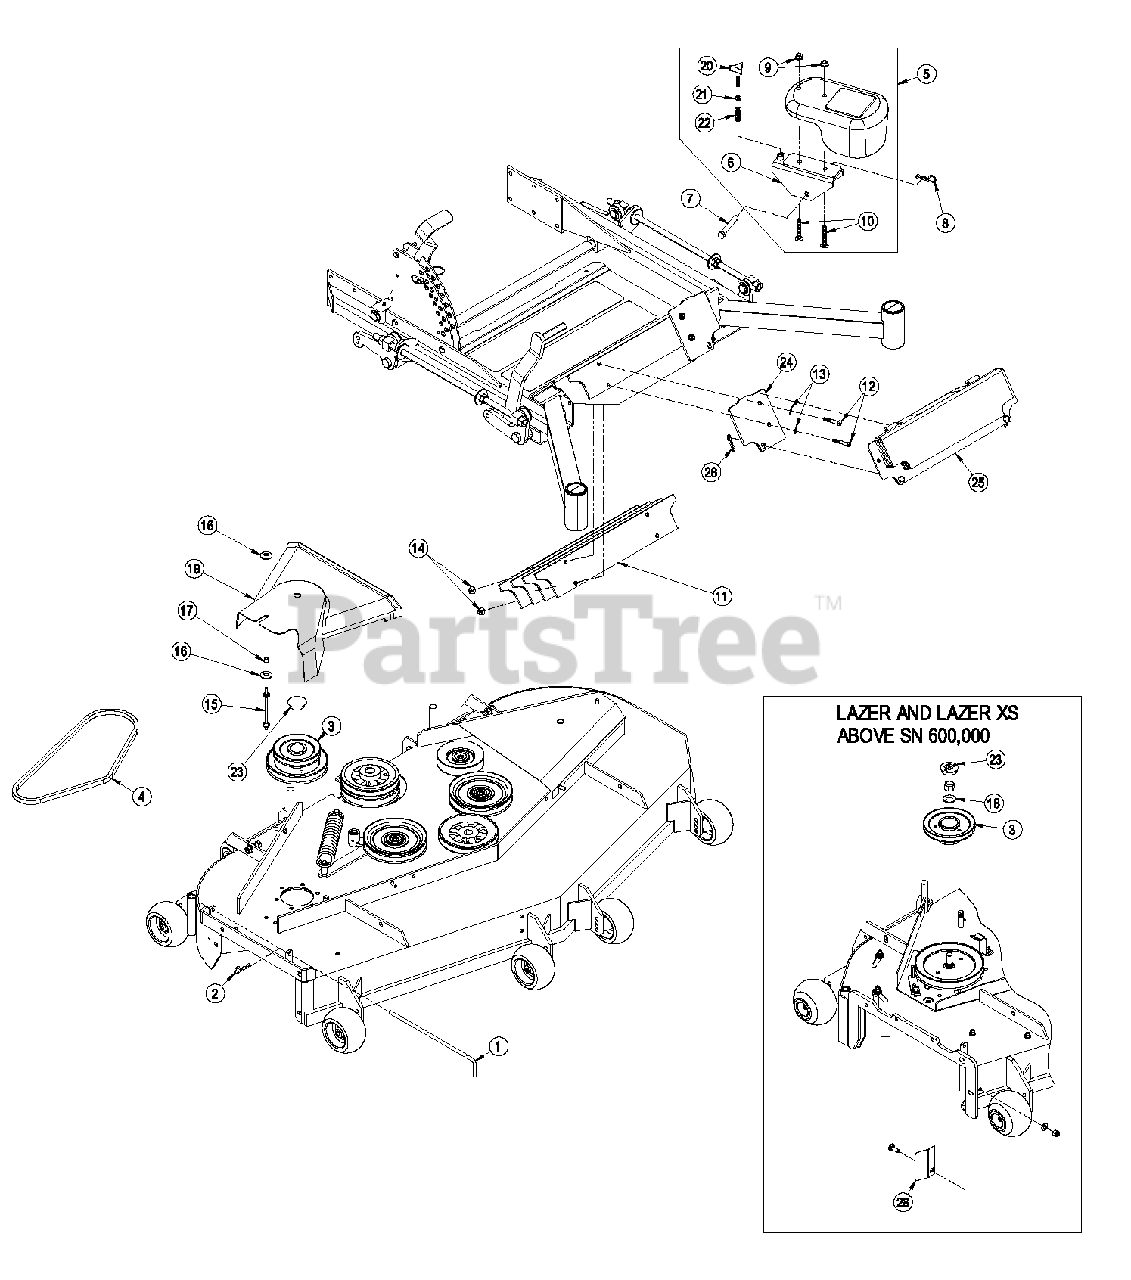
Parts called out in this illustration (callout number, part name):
1	PIN,CHUTE PIVOT
2	PIN-COTTER
3	JACKSHAFT, LZUV72
4	BELT, BLOWER DRIVE 72
5	ASM, WEIGHT 2.0" 43 POUND
6	WLD, BRACKET 2.0 ARM
7	PIN-CLEVIS
8	PIN-COTTER
9	NUT-HHF, WHIZ
10	BOLT-SQH
11	PLATE, WEIGHT
12	SCREW-HH
13	WASHER-PLAIN
15	STUD,BELT SHIELD 4 INCH
17	Spacer, Grommet
18	Washer, 5/8 SAE
19	COVER, BELT 72
23	PLUG, BLACK NYLON 1.75
24	PLATE, WEIGHT MOUNTING
25	ASM, WEIGHT PLATE WITH DE
26	PIN-HAIR
28	Deflector
